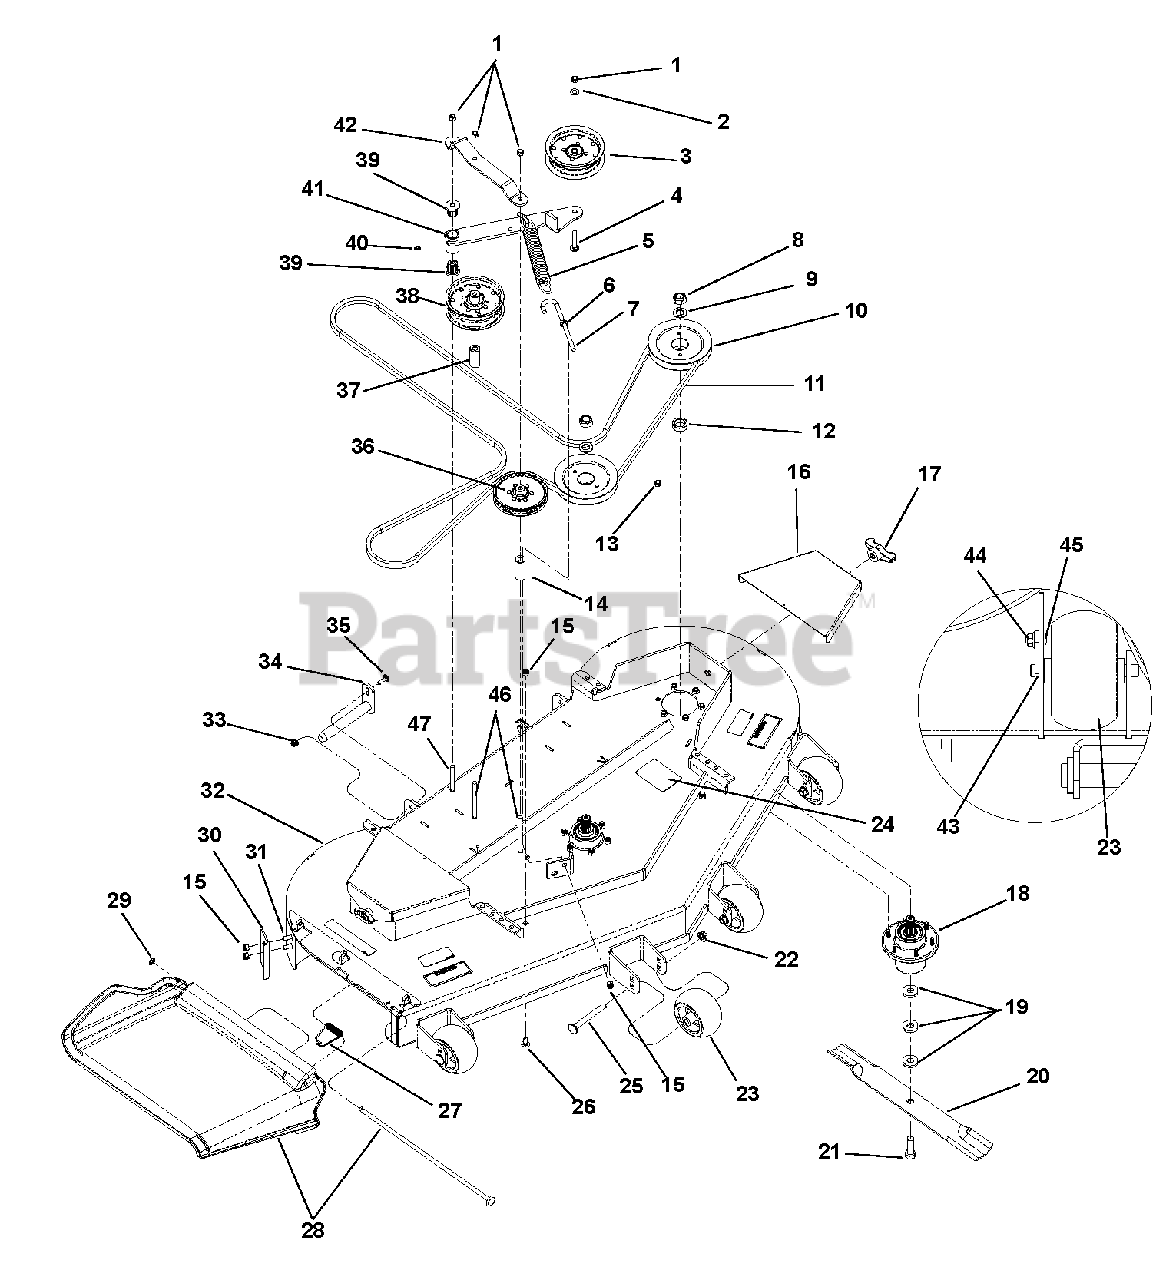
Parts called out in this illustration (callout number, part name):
1	LOCKNUT, 3/8-16 CROWN Y
2	WASHER, .406 X .813 X .065 FLAT Y
3	PULLEY, FLAT 5.0 X .38 W/ BRG
4	BOLT, 3/8-16 X 2.25 CRG 5 Y
5	SPRING, DECK IDLER
6	LOCKNUT, 3/8-16 WHIZ Y
7	J-HOOK, IDLER
8	LOCKNUT, 3/4-16 CROWN C
9	WASHER, .75 X 1.3125 X .113
10	HUB, LARGE PULLEY TALL
12	SPACER, 1.500 X 1.000 X .510 Y
13	NUT, 3/8-16 STD HEX GR5 Y
14	SPACER, .437 X 1.00 X 2.50 SMLS
15	LOCKNUT, 3/8-16 NYLOC Y
16	COVER, BELT
17	KNOB, LOCKING
18	ASSY, SPINDLE HOUSING
19	WASHER, BLADE
20	BLADE, 20.940 LO-LIFT
21	BOLT, 5/8-11 X 2.00 HEX 8 Y
22	LOCKNUT 1/2 W/ FLANGE
23	WHEEL, GAGE
24	DECAL, BELT PATH
25	BOLT, 1/2-13 X 4.50 CRG 5 Y
26	BOLT,3/8-16 X 3/4 CAR GR5 LNNK
27	SPRING, DISCHARGE CHUTE
28	CHUTE, ASSY
29	RETAINER #
30	PLATE, EXTENDER 48" HYDRO
31	BOLT, 3/8-16 X 1.00 CRG 5 SN Y
32	ASSY, 61 DECK w/ DECALS
33	LOCKNUT, FL, ISO7043, M8 X 1.25
34	PIN, WELDED
35	BOLT, RH, SQNECK, JDS137, M8 X 1.25
36	PULLEY, FLAT 5.00 X .375 W/ BRG
37	SPACER, .437 X 1.00 X 2.25 SMLS
38	PULLEY, FLAT 5.25 X .375 W/BRG
39	BRG, FLG M10 X M25 X M27 FLUTED
40	FTG, 1/4-28 STRGT GREASE ZERK
41	ARM, IDLER
42	STRAP, IDLER PULLEY
43	PIVOT, RETAINER WELD
44	NUT-1/4" FLANGE PREVAILING TOR
45	BOLT, 1/4-20 X .750 CRG 5 Y
46	BOLT, CAR 3/8-16 X 5.00
47	BOLT, 3/8-16 X 3.50 CRG 5 Y
